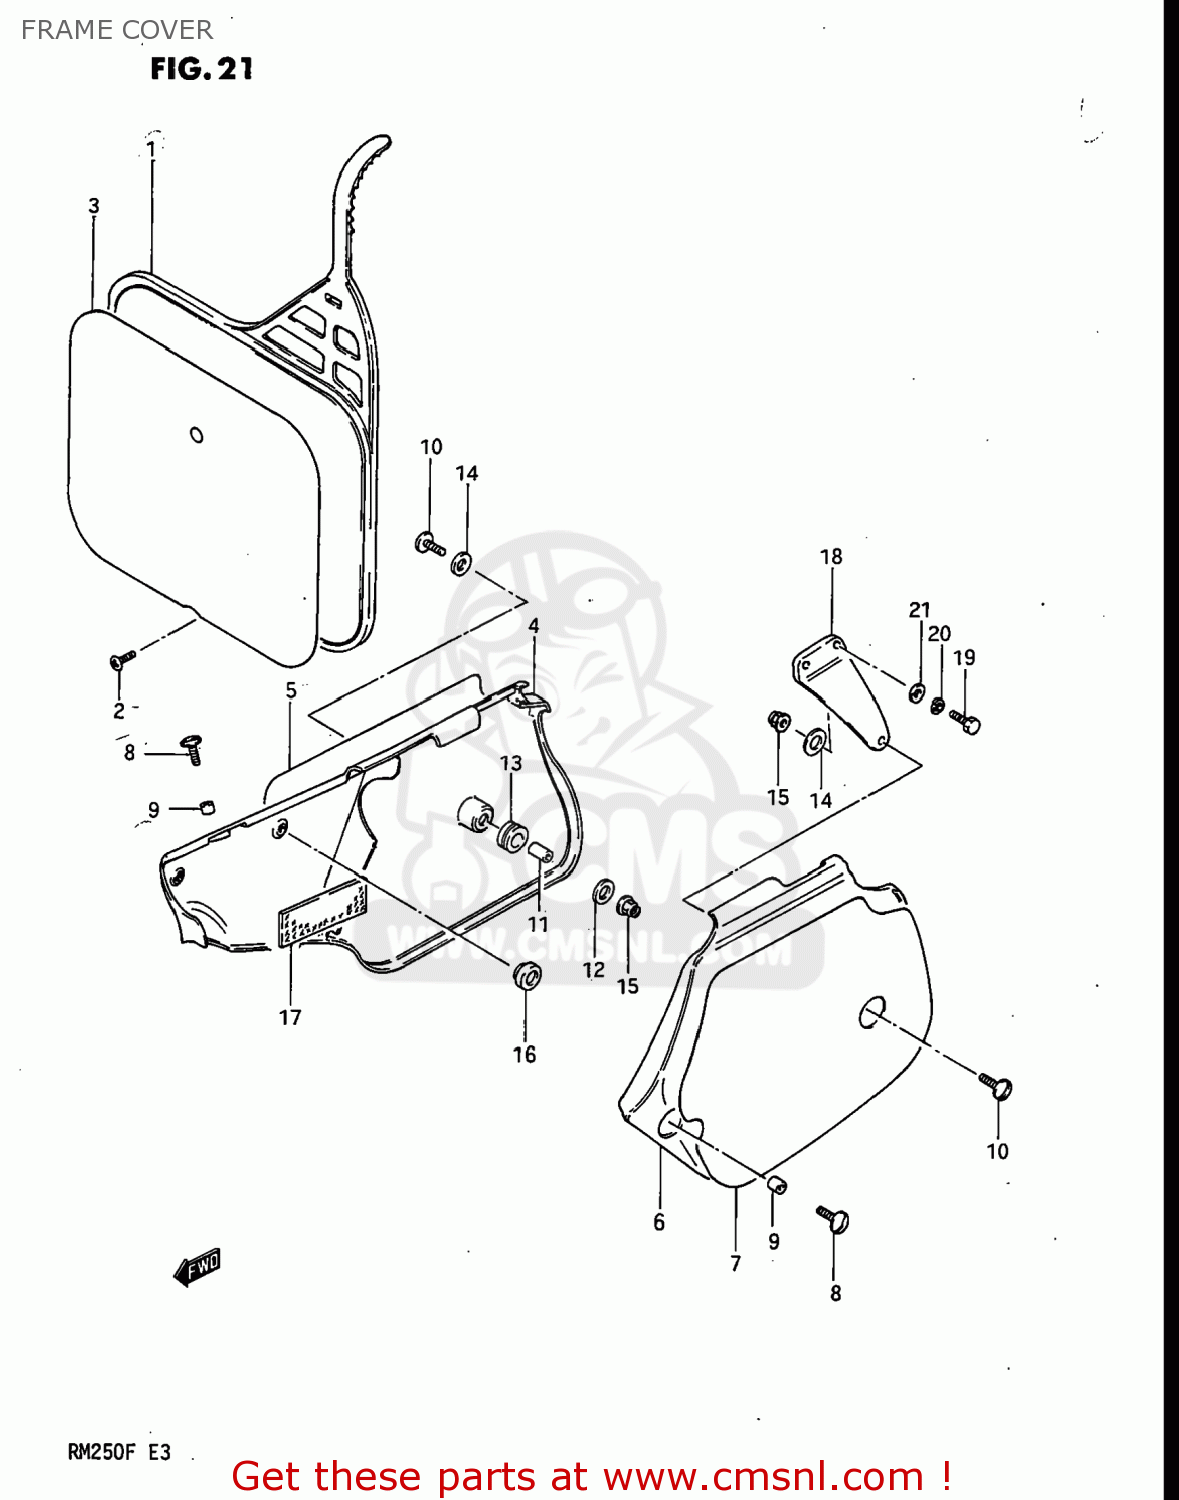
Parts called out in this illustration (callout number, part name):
1	PLATE,NUMBER,FRONT
2	SCREW
3	EMBLEM,FRONT NUMBER PLATE
4	COVER,FRAME,RIGHT
5	EMBLEM
6	COVER,FRAME,LEFT
7	EMBLEM,NUMBER PLATE,LEFT
8	SCREW(6X14)
9	SPACER (6.1X8X3.5)
10	SCREW(6X20)
11	SPACER (6.1X9X9)
12	WASHER (6.5X24X1.6)
13	CUSHION
14	WASHER FRAME COVER
15	NUT 6MM
16	CUSHION
17	HEAT SHIELD,FRAME COVER
18	STAY,FRAME COVER,LEFT
19	BOLT
20	WASHER,LOCK
21	WASHER(6.5X16X1.2)
